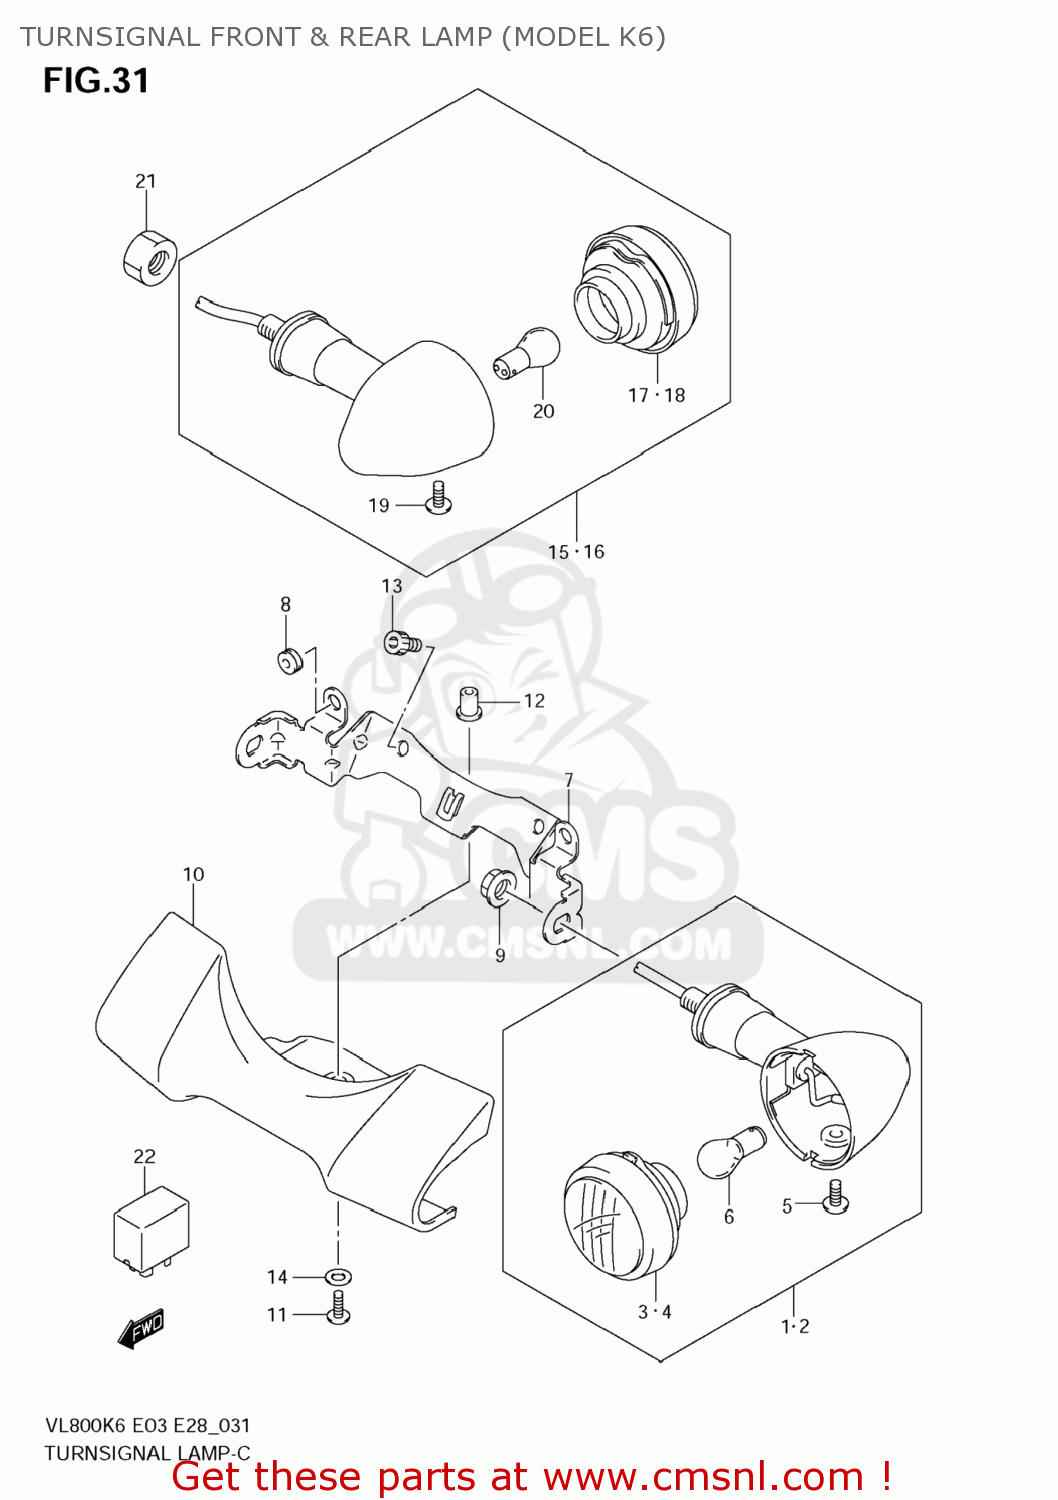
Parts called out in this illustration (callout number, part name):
1	LAMP ASSY,FR TURN SIGNAL,R
2	LAMP ASSY,FR TURN SIGNAL,L
3	LENS
4	LENS
5	SCREW(4X10)
6	BULB(12V21/5W)
7	BRACKET
8	CUSHION
9	NUT
10	COVER,FRONT TU
11	SCREW(5X16)
12	NUT
13	PLUG
14	WASHER(5.5X14X1.2)
15	LAMP ASSY,RR TURNSIGNAL,R
16	LAMP ASSY,RR TURNSIGNAL,L
17	LENS
18	LENS
19	SCREW(4X10)
20	BULB(12V21W)
21	NUT
22	RELAY ASSY,TURNSIGNAL LAMP
